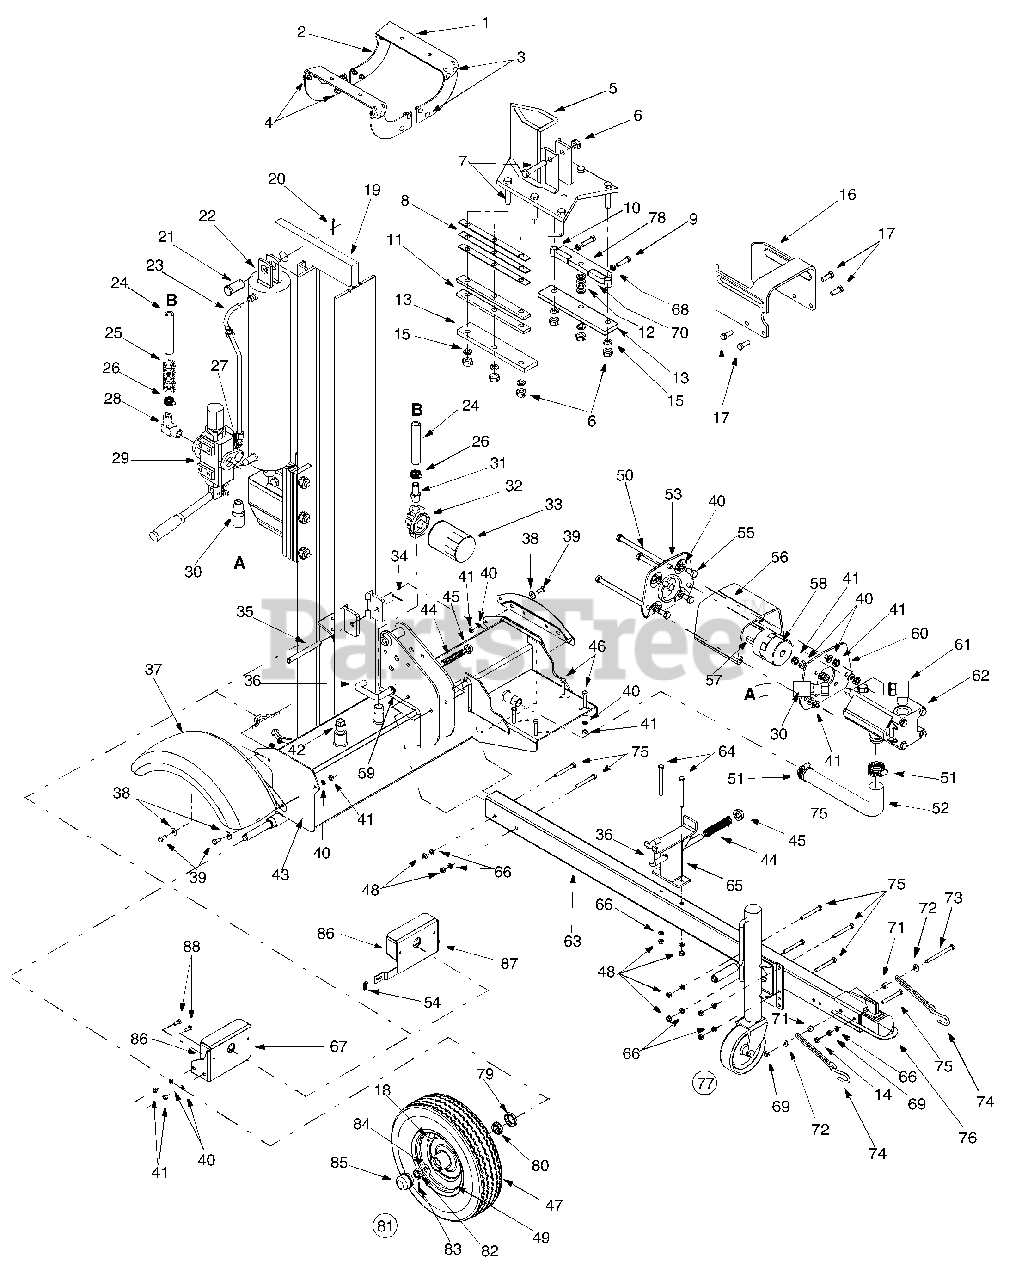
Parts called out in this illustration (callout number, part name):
4	Flanged Lock Nut, 3/8-16
7	Hex Head Screw, 1/2-20 x 2.75
10	Spacer
12	Flat Washer, .531 ID x .94 OD
14	Hex Jam Nut, 3/8-16
15	Lock Washer, 1/2
17	Hex Cap Screw, 3/8-16 x 1
18	Valve
21	Clevis Pin
22	Kit Seal 5.0" for Best Metals cylinder 718-0313
22	Hydraulic Cylinder
22	Kit Seal 5.0" for XINGHUI cylinder 718-0313A
22	Kit Seal 5.0" for ENERGY cylinder 718-0313A
23	Hydraulic Tube
24	Return Hose, 3/4 x 44 Lg
25	Hose Guard
26	Hose Clamp
27	Tube Adapter
28	Return Elbow
30	High Pressure Hydraulic Hose
32	Filter Head
33	Oil Filter
34	Cotter Pin
35	Hinge Pin
36	Locking Rod
39	Hex Cap Screw, 5/16-24 x .75
40	Lock Washer, 5/16
41	Hex Nut, 5/16-24
42	Pipe Plug
46	Hex Cap Screw, 5/16-24 x 1.75
47	Tire, 16 x 4.8
48	Hex Nut, 3/8-16
49	Rim Assembly
50	Hex Cap Screw, 5/16-24 x 5.25
51	Hose Clamp
52	Suction Hose
54	Speed Clip
55	Hex Cap Screw, 5/16-24
56	Coupling Shield
57	Key, 1/4 x 2
58	Flex Coupling
59	Flat Washer, .63 x .93 x .060
62	Gear Pump (16 GPM)
64	Hex Screw, 3/8-16 x 4.0
69	Hex Lock Nut, 3/8-16
70	Adjustable Gib, 5/8 x 5/8 x 2
72	Flat Washer, 3/8" ID x .87" OD
73	Hex Bolt, 3/8-16 x 4.25
74	Chain
75	Hex Bolt, 3/8-16 x 3
76	Hitch Coupler
77	Adjustable Jack Stand Assembly
79	Bearing Seal
80	Tapered Bearing
81	Wheel Assembly
82	Slotted Nut, 3/4-16
83	Cotter Pin
84	Flat Washer, .760 ID x .500 OD
86	Tail Light Assembly
